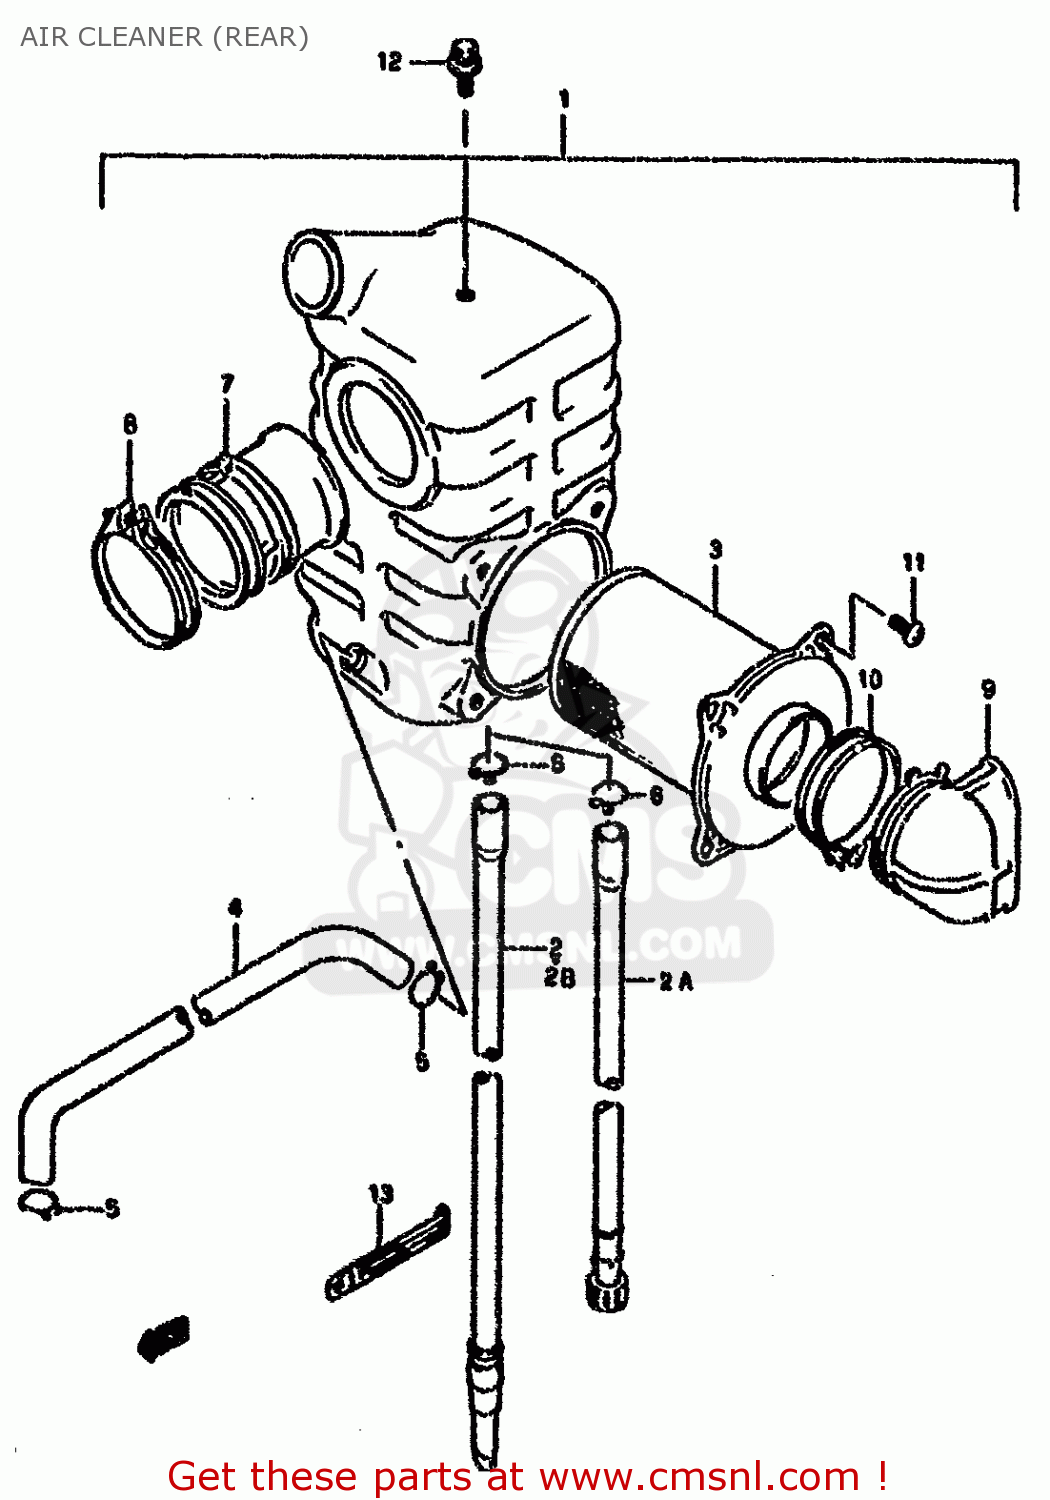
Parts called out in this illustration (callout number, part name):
1	CLEANER ASSEMBLY,AIR,REAR
2	TUBE,DRAIN
2A	TUBE,DRAIN
2B	TUBE,DRAIN
3	FILTER ASSY,AIR
4	TUBE,BREATHER
5	CLIP
6	CLIP
7	TUBE,OUTLET
8	CLAMP
9	TUBE,INLET
10	CLAMP
11	SCREW
12	BOLT
13	CLAMP
